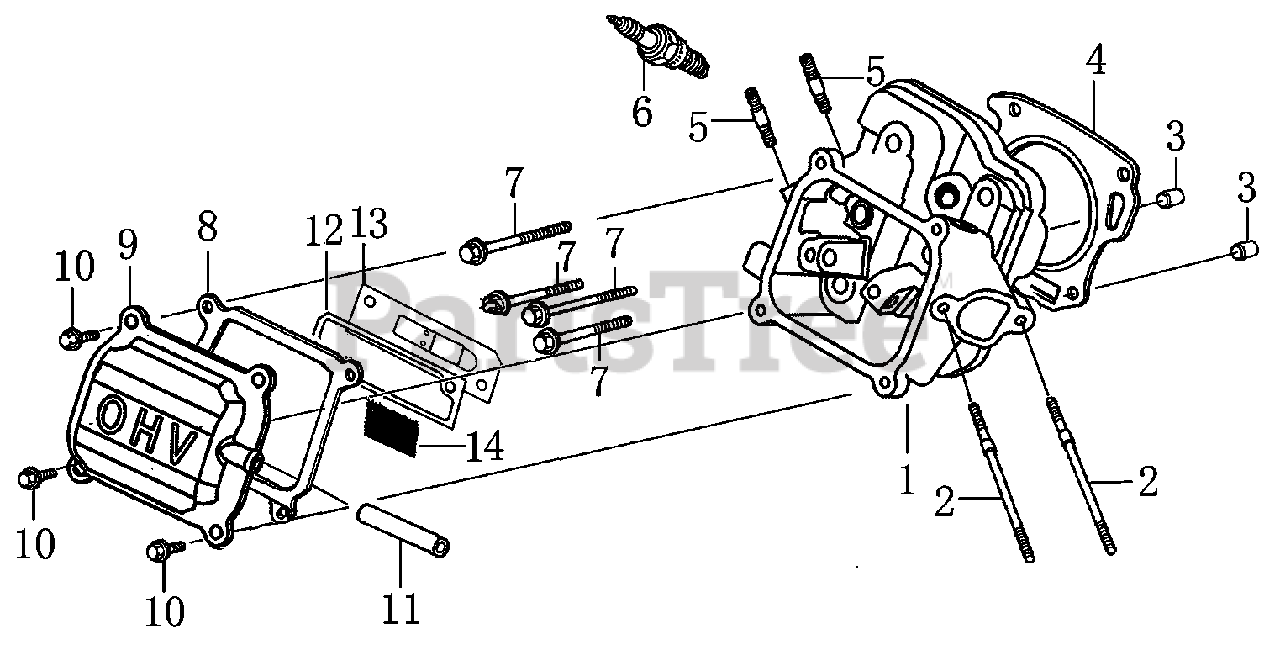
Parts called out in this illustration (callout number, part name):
1	HEAD, CYLINDER
2	BOLT, STUD , IN.
3	PIN, DOWEL
4	GASKET, CYLINDER HEAD
5	BOLT, STUD, EX.
6	PLUG SPARK
7	BOLT, HEAD, FLANGED
8	GASKET, VALVE COVER
9	COVER, VALVE
10	BOLT, FLANGE
11	TUBE, BREATHER
12	GASKET, BREATHER CHAMBER
13	CAP, BREATHER CHAMBER
14	STRAINER, OIL
